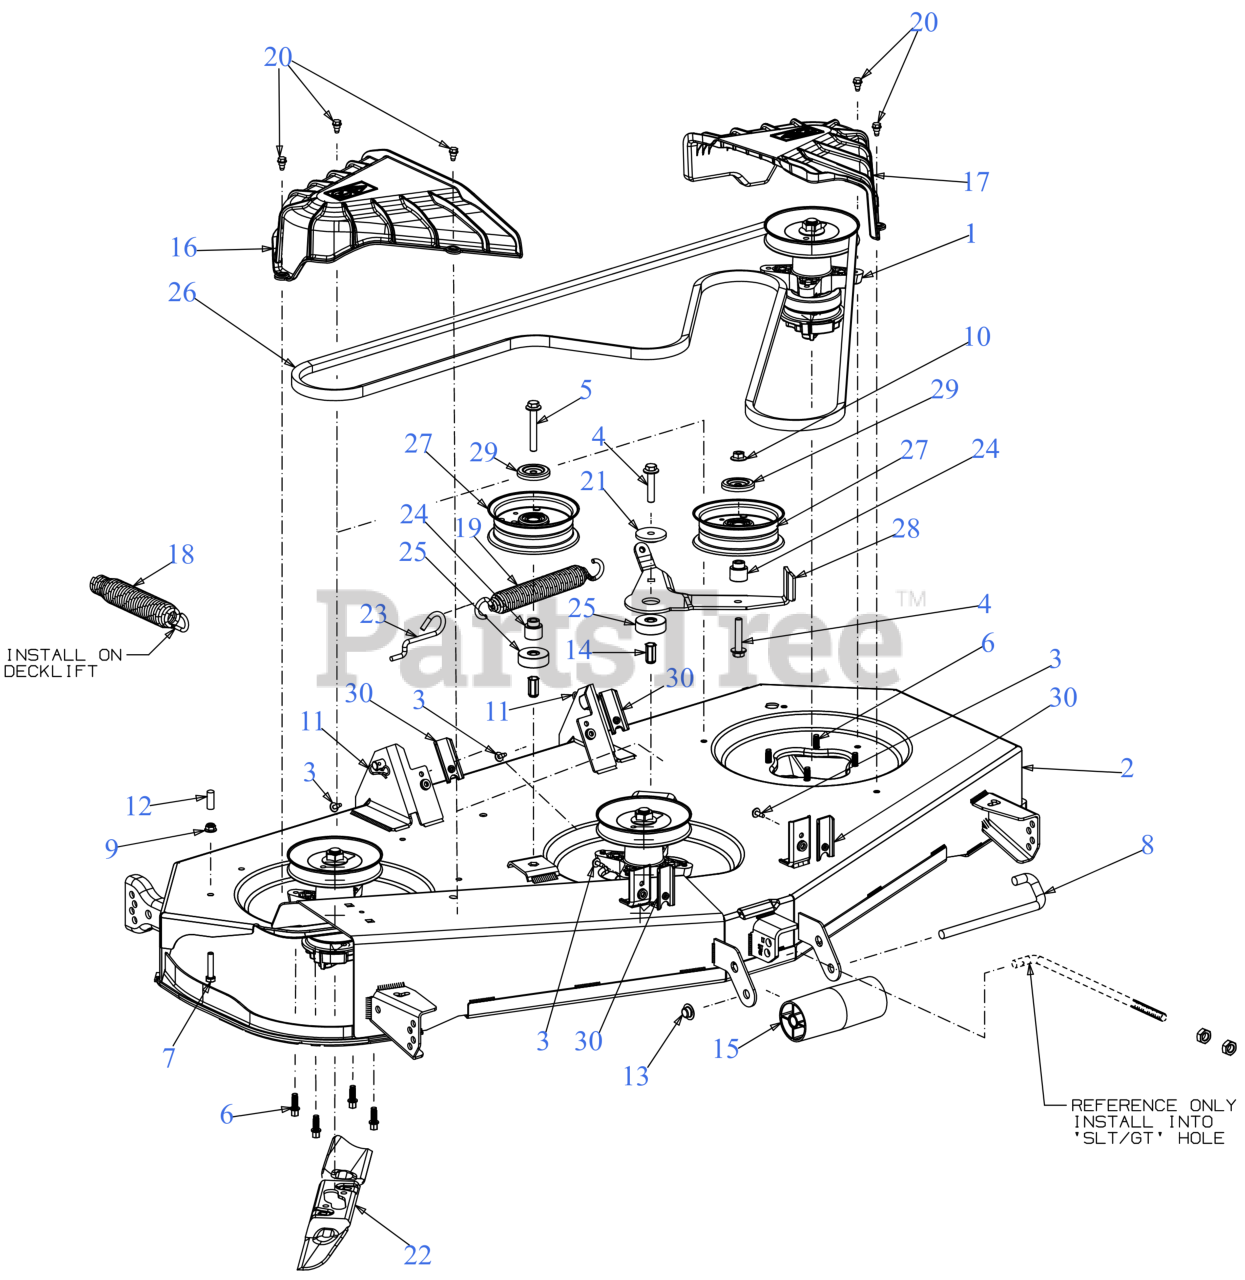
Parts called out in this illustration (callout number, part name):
1	BLADE SPINDLE ASSEMBLY
2	54" FAB DECK SHELL
3	SCREW M6-1 x .625
4	SCREW 3/8-16 x 2.0
5	SCREW 3/8-16 x 2.75 GR5
6	SCREW 5/16-18 x .875
7	SCREW 5/16-18 x 1.5 LG
8	ROLLER PIN 1/2 x 7.31
9	FLANGE LOCK NUT 5/16-18
10	FLANGE LOCK NUT
11	BOW TIE COTTER PIN
14	NUT RIVET 3/8-16
16	SPINDLE COVER (RH)
17	SPINDLE COVER (LH)
18	LIFT ASSIST SPRING (LARGE)
19	SPRING 1.25" DIA x 8.5" LONG
20	SHOULDER SCREW 1/4-20 x .50
21	SHOULDER SPACER
22	54" HIGH-LIFT FASTATTACH BLADE
22	Cub Cadet 50"/54" DETHATCHING BLADE SET
22	54" FASTATTACH XTREME MULCH BLADE
22	54" LOW-LIFT SAND FASTATTACH BLADE
23	DECK SPRING HOOK
24	SHOULDER SPACER
25	SPACER .385ID x 1.75OD x .585THK
26	V-BELT B SEC x 139
26	Cub Cadet 54" DECK DRIVE BELT
26	Genuine Factory Parts 54" DECK BELT
27	IDLER PULLEY 4.50" DIA
28	IDLER PIVOT BRACKET
29	IDLER PULLEY CAP
